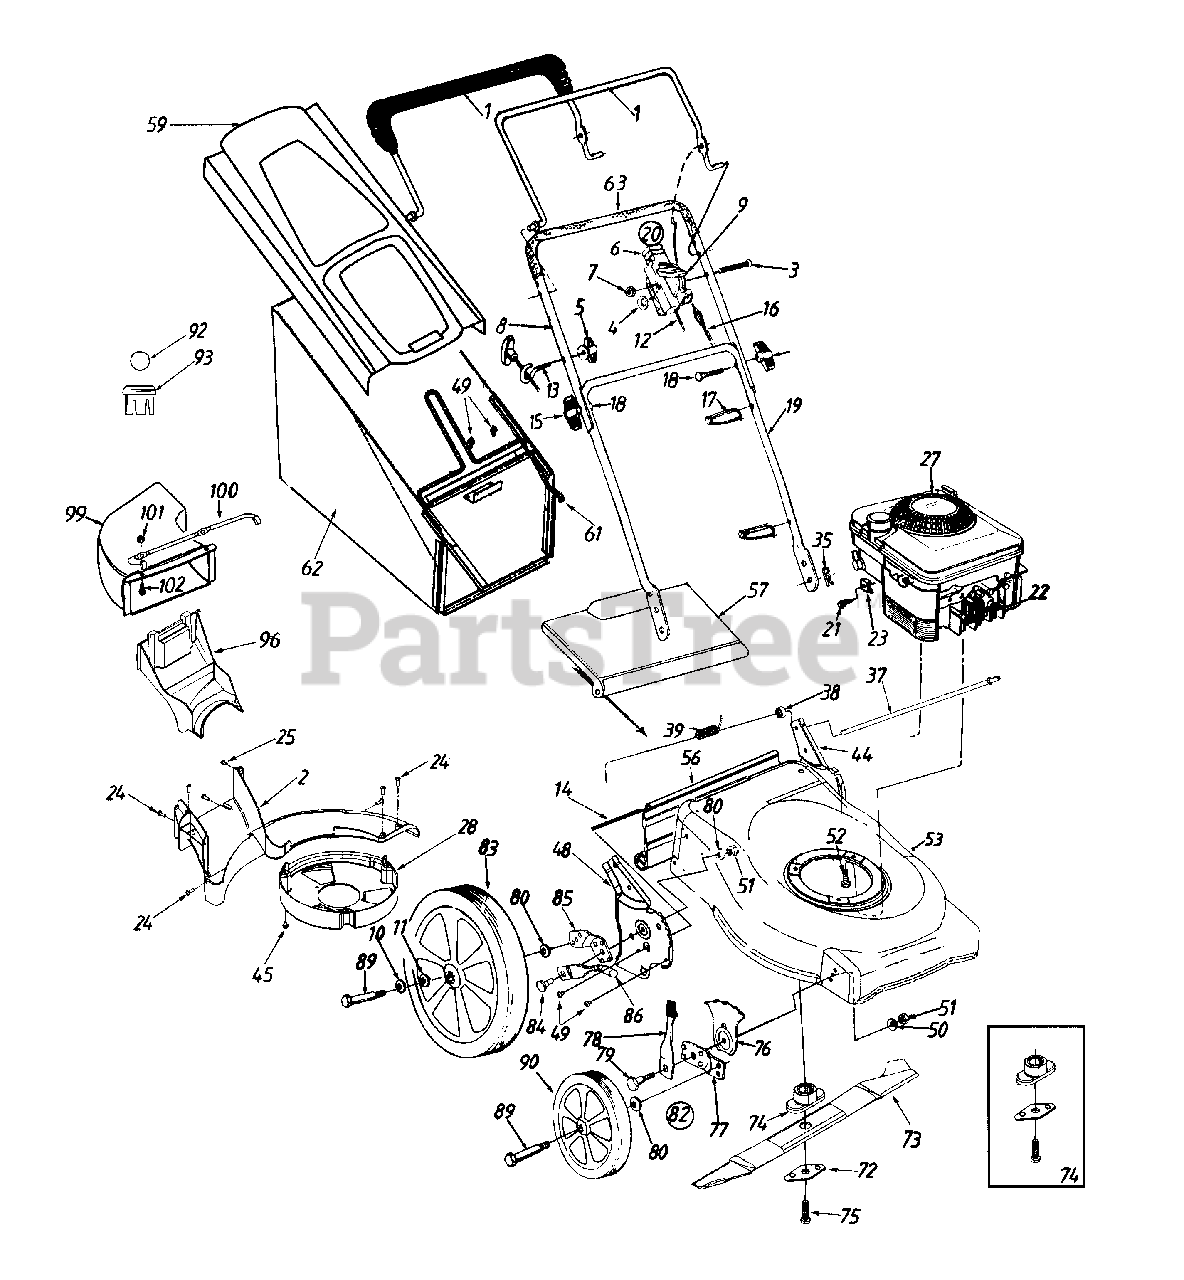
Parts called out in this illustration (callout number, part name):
2	Baffle
3	Oval C-Sunk Mach.-Scr.
4	Spr. Wash..66"I.D.
5	Handle Knob 1/4-20 Thd.
6	Throttle Body
7	Hex L-Nut 1/4-20
10	Wash. 1/2" I.D.
11	Spring Washer
12	Throttle Control Wire-60"
13	Rope Guide
14	Wire-47"Lg.
15	Hand Knob
16	Control Cable 43"
17	Cable Tie
18	Curved Hd. Bolt 5/16-18 x 2" Lg.
20	Throttle Box Comp.
21	Hex Self-Tap Scr. #10-32 x .62" L
22	Spark Plug Boot
23	Cable Clamp (B&S)
24	Screw H.L. 12-24
25	Screw Mach. B Tapp.
27	Engine
28	Belt Guard
35	Int. Cotter Pin 5/15" Dia.
37	Pivot Rod
38	Spacer .385 I.D.
39	Torsion Spring L.H.
50	Bell-Wash. .39"I.D.
51	Hex Nut 3/8-16 Trd.
52	Hex L-Wash. Hd. Scr. 3/8-16 x 1" Lg.
62	Grass Bag - Black
63	Foam Grip
72	Blade Bell Support
73	21" Mulching Blade w/Star
74	Blade Adaptor Kit w/Star
75	Hex Bolt 3/8-24x 2.5 Lg.
76	Height Adj. Plate
78	Spring Lever Ass'y w/Knob
79	Shld. Bolt .50" Dia x .357"
80	Bell-Wash. .38" I.D. x .88" O.D.
82	Height Adj. Ass'y Comp. R.H.
83	Wheel Ass'y Comp. - Rear
84	Shoulder Screw 1/2" Dia. x .434"
85	Pivot Bar R.H.
86	Foam Grip
89	Axle Bolt Front
90	Wheel Ass'y Comp.- Front
92	Ball - Flo Indicator
93	Housing- Flo Indicator
96	Mulch Plug
99	Chute Deflector
100	Chute Mounting Rod
101	Hex L-Nut 1/4-20 tHD.
102	Mach. Scr. 1/4-20 x .5" Lg
